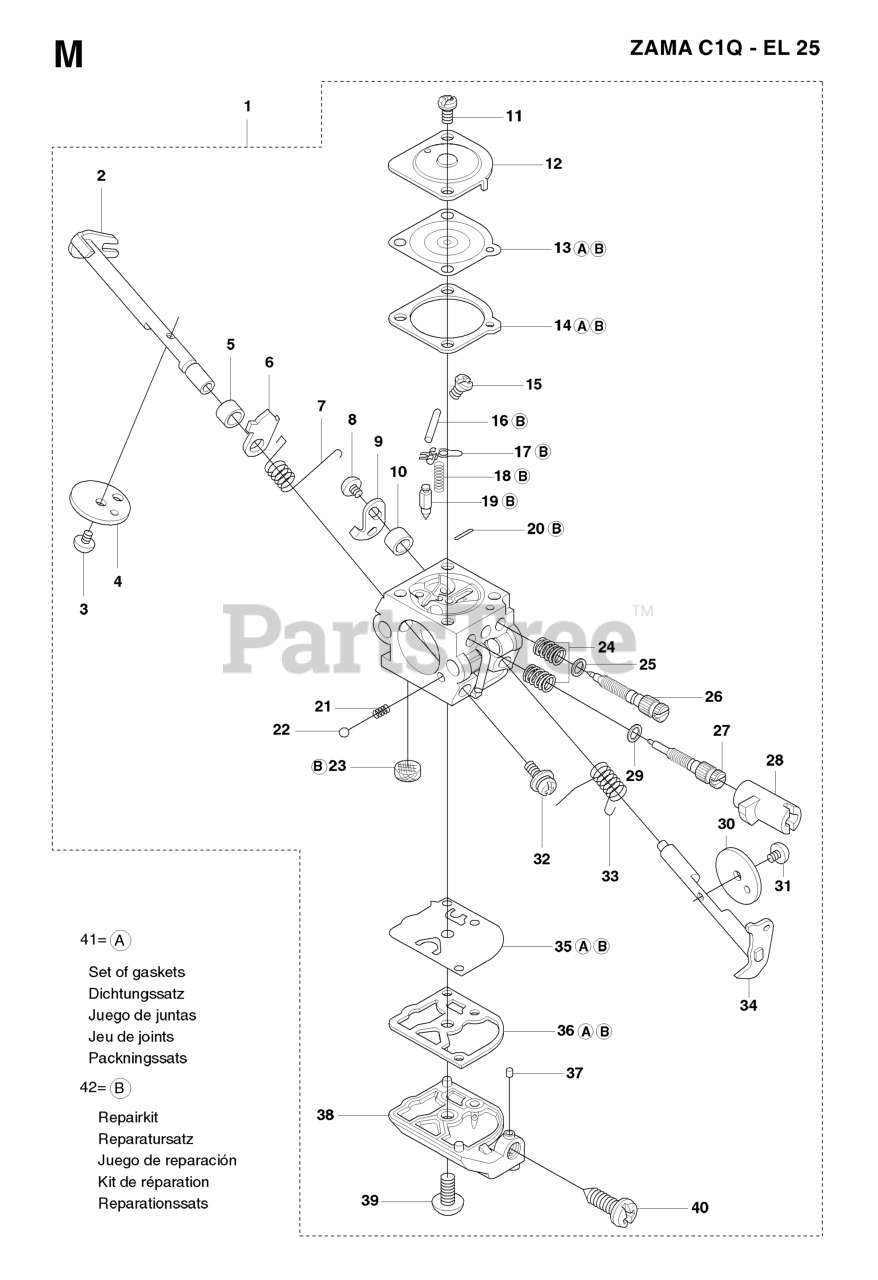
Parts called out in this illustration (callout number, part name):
1	CARBURETOR
2	CHOKE SHAFT
4	DISC
10	LEVER
16	PIN RETAINING SCREW
18	SPRING
19	INLET NEEDLE
24	SPRING
26	LOW SPEED NEEDLE
27	NEEDLE HIGH SPEED
30	THROTTLE FLAP
33	SPRING THROTTLE
35	PUMP DIAPHRAGM
41	GASKET KIT (ZAMA GND39)
42	CARBURETOR KIT (ZAMA RB69)
